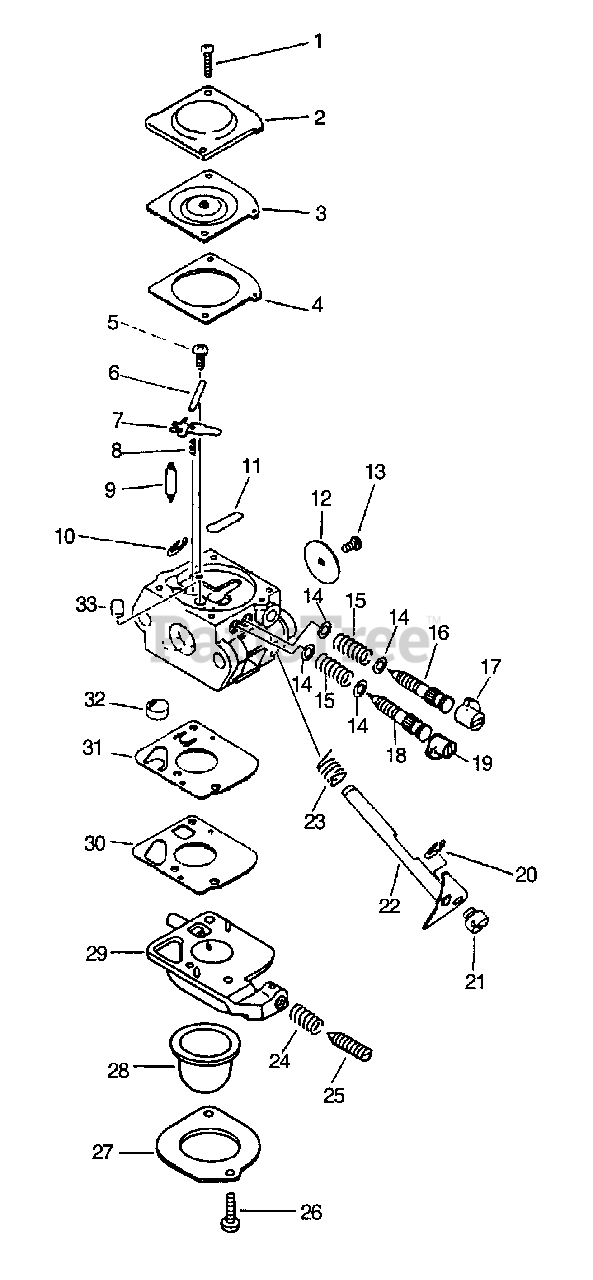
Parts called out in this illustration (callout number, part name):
2	COVER, METERING
3	DIAPHRAGM, METERING
4	GASKET, METERING
5	SCREW, METERING LEVER PIN
6	PIN, METERING LEVER
7	LEVER, METERING
8	SPRING, METERING LEVER
9	VALVE, NEEDLE
10	RING, RETAINING
11	PLUG, WELCH
12	VALVE, THROTTLE
16	NEEDLE - LOW SPEED
17	CAP, LIMITER
18	NEEDLE - HIGH SPEED
19	CAP, LIMITER
20	RING, RETAINING
22	SHAFT, THROTTLE
23	SPRING, RETURN
24	SPRING, IDLE ADJUST
25	SCREW, IDLE ADJUST
26	SCREW, RETAINER
27	RETAINER, PURGE BULB
28	BULB, PURGE
29	BASE, PURGE
30	GASKET, PURGE
31	DIAPHRAGM, PURGE
32	STRAINER
33	NOZZLE, CHECK VALVE
